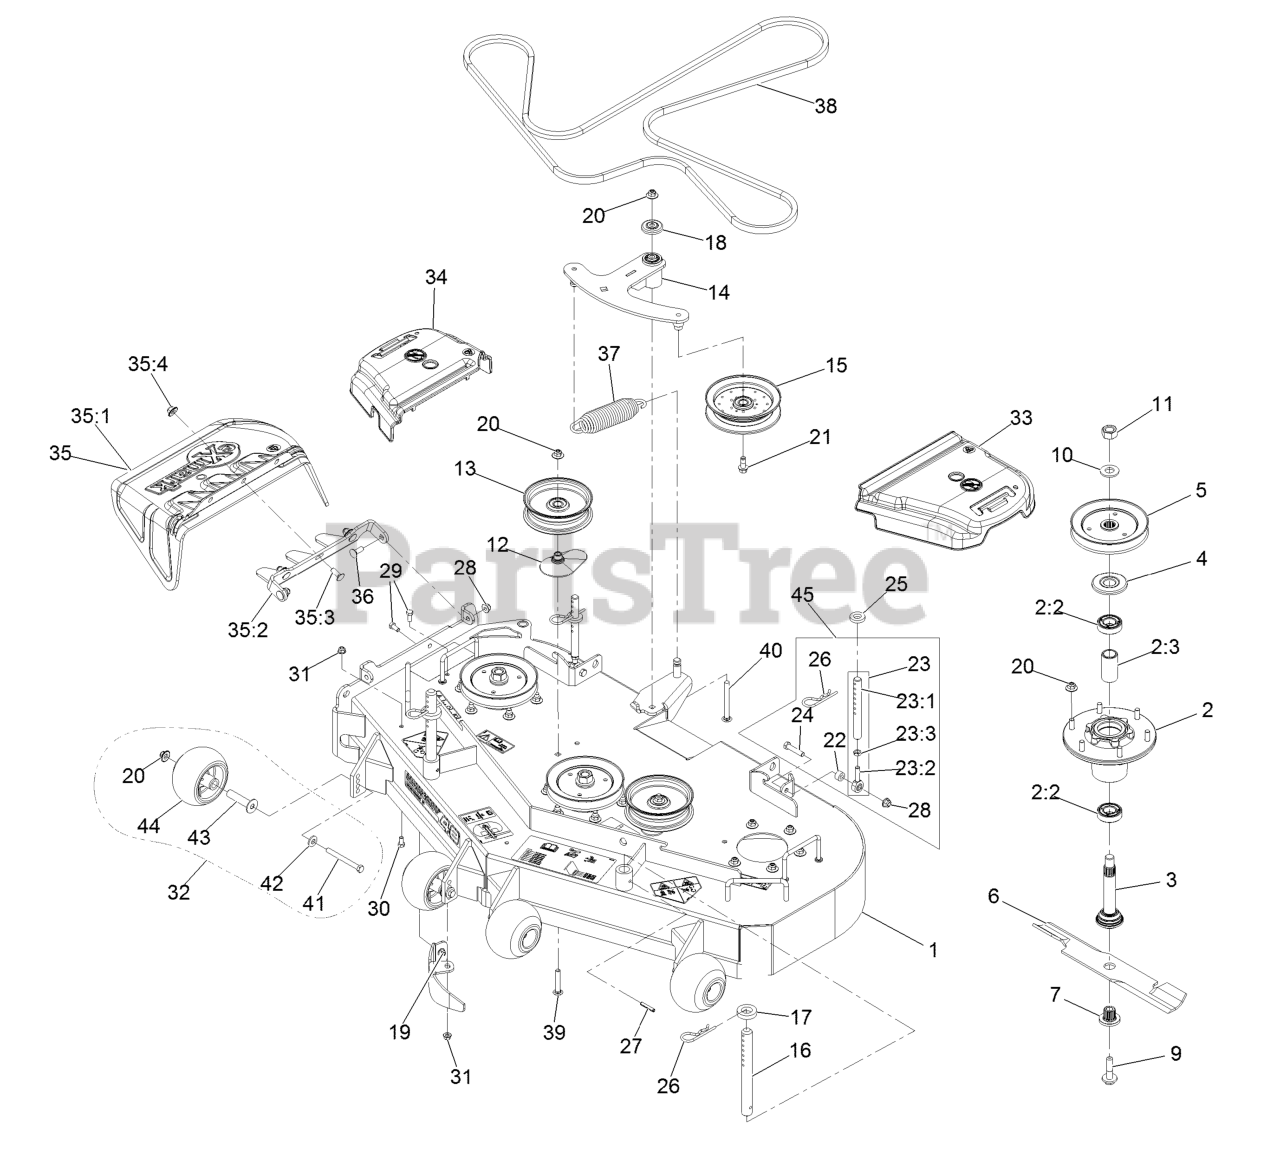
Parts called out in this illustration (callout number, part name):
1	ASM, Deck 48" W/Decals
2	ASM-Cutter Hsg With Bearings
2:2	Bearing-Ball
2:3	Spacer-Bearing
3	ASM-Spindle And Seal
4	Guard,Bearing Top .989
5	Sheave,Blade Drive 5.90
6	Blade-Extreme 2, 16.25"
6	Blade-Notched
6	Blade, Mulching
6	Blade, Low Lift
6	Blade, Solid
7	Bushing, Splined
9	Screw,Sems (1/2-20 X 2.19 GR5)
11	Nut-Hex
12	Spacer-Pulley
13	Idler-Pulley, Flat
14	ASM, Deck Idler
15	Idler-Pulley, Flanged
16	Rod, Deck Support
17	Spacer-Deck Support
18	Guard-Top
19	Baffle, Dogleg
20	Nut-Flange, NI
21	Screw-Hfh
23	Link Assy
23:1	Link, Rear Deck Support
23:2	Balljoint
23:3	Nut-HJ
24	Screw-HH
26	Hairpin, .177
27	Roll Pin, 1/4 X 1-1/2
28	Nut-HF, NI
29	Screw-HH
30	Screw-HH
31	Nut-HF, NI
32	Kit, Anti-Scalp Roller
33	Cover-Belt, LH
34	Cover-Belt, RH
35	ASM, Discharge Chute
35:1	Chute, Discharge
35:2	Bracket, Discharge Chute
35:3	Screw-CARR
35:4	Nut-Flange, NI
36	Screw-CARR
37	Spring-Extension
38	Belt, Deck
39	Bolt-CARR, Short Neck
40	Screw-CARR
41	Screw-HH
42	Washer-Belleville
43	Axle, Roller
44	Roller-Anti-Scalp
45	Kit, Support Link W/Pin
